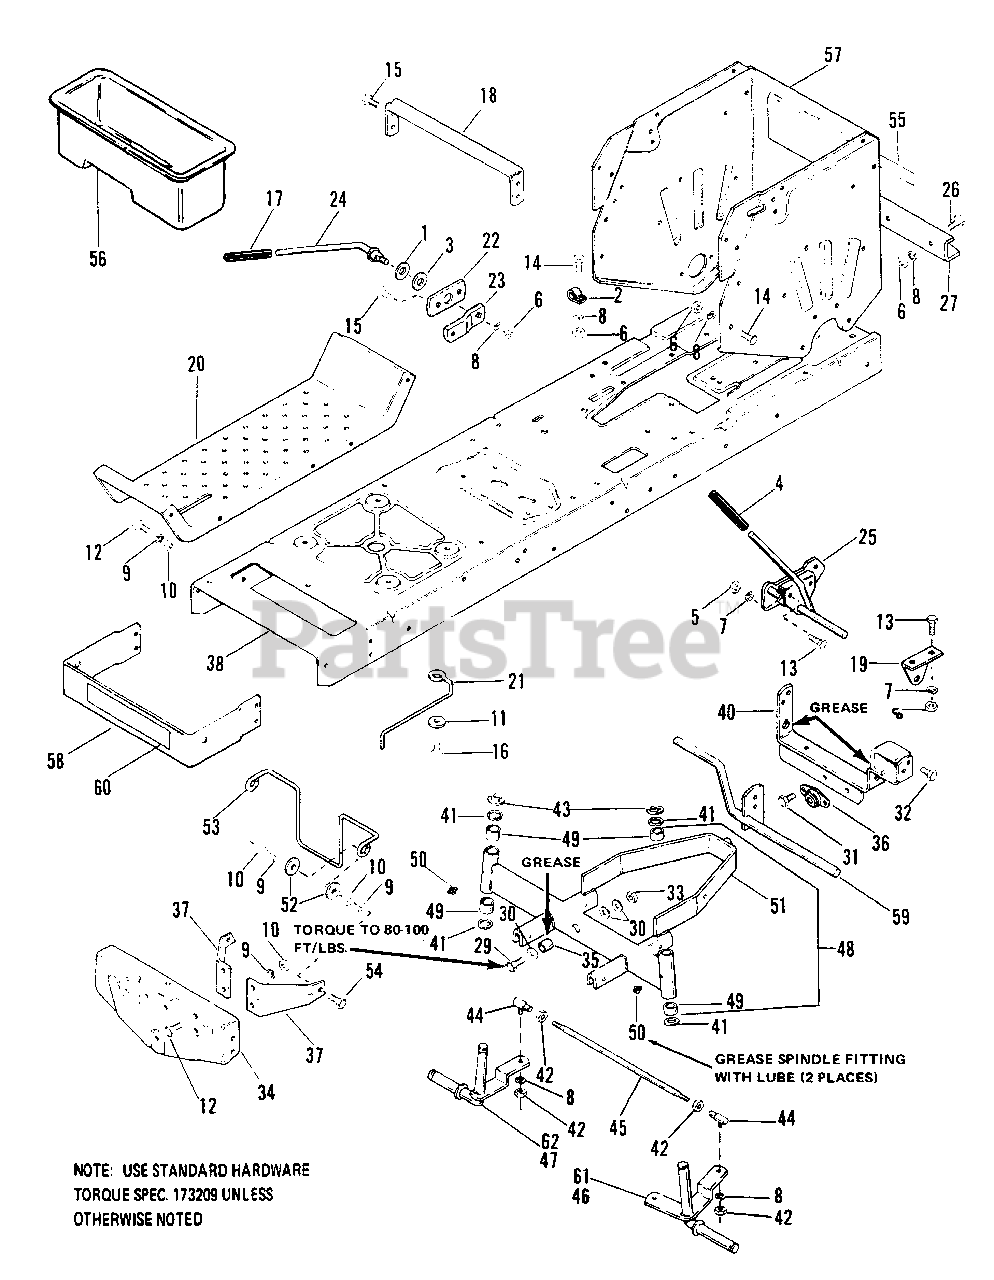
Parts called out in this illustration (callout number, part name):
1	WASHER, Steel
3	WASHER, Nylon
4	HANDLE, Grip
5	NUT, Hex, 1/4-20
6	NUT, Hex, 3/8-16
7	LOCKWASHER, Spring, 1/4
8	LOCKWASHER, Spring, 3/8
9	LOCKWASHER, Spring, 5/16
10	NUT, Hex, 5/16-18
11	WASHER, Plain, 5/16
12	CAPSCREW, Hex Hd., 5/16-18 x 3/4
13	CAPSCREW, Hex Hd., 1/4-20 x 5/8
14	CAPSCREW, Hex Hd., 3/8-16 x 3/4
15	SCREW, Tapping, 5/16-18 x 1/2
16	SCREW, Tapping, 5/16-18 x 7/8
17	GRIP
18	BRACE, Seat
19	SUPPORT, Clutch
21	STOP, Belt
22	BAR, Support
23	ARM, Lift
24	HANDLE, Lift
25	LEVER ASSY, Clutch
26	CAPSCREW, Hex Hd., 3/8-16 x 1
27	BAR, Draw
29	CAPSCREW, Hex Hd., 1/2-13 x 1-1/2
30	WASHER, Plain, 5/16
31	SCREW, Washer Hd., 3/8-16 x 1/2
32	SCREW, Hex Washer Hd., 5/16-18 x 5/8
33	LOCKNUT, 1/2-13
34	FRONT AXLE SUPPORT
36	BEARING ASSY, Side Range
37	BRACE, Front Axle
40	SUPPORT ASSY, Axle
42	NUT, Hex Jam, 3/8-24
43	RING, Retaining
44	BALL JOINT ASSY
46	SPINDLE ASSY, L.H. (6010 Only)
47	SPINDLE ASSY, R.H. (6010 Only)
48	AXLE ASSY, Front
50	FITTING, Lube
51	FRONT AXLE, w/o Bushings
52	WASHER, Plain, 1/4
53	STOP, Belt
54	CAPSCREW, Hex Hd., 5/16-18 x 1-1/2
55	DECAL, Transaxle
56	TOOL TRAY
57	SUPPORT, Axle (Rear Frame)
59	LEVER ASSY, Brake
60	DECAL, Simplicity
61	SPINDLE ASSY, L.H. (6008 Only)
62	SPINDLE ASSY, R.H. (6008 Only)
